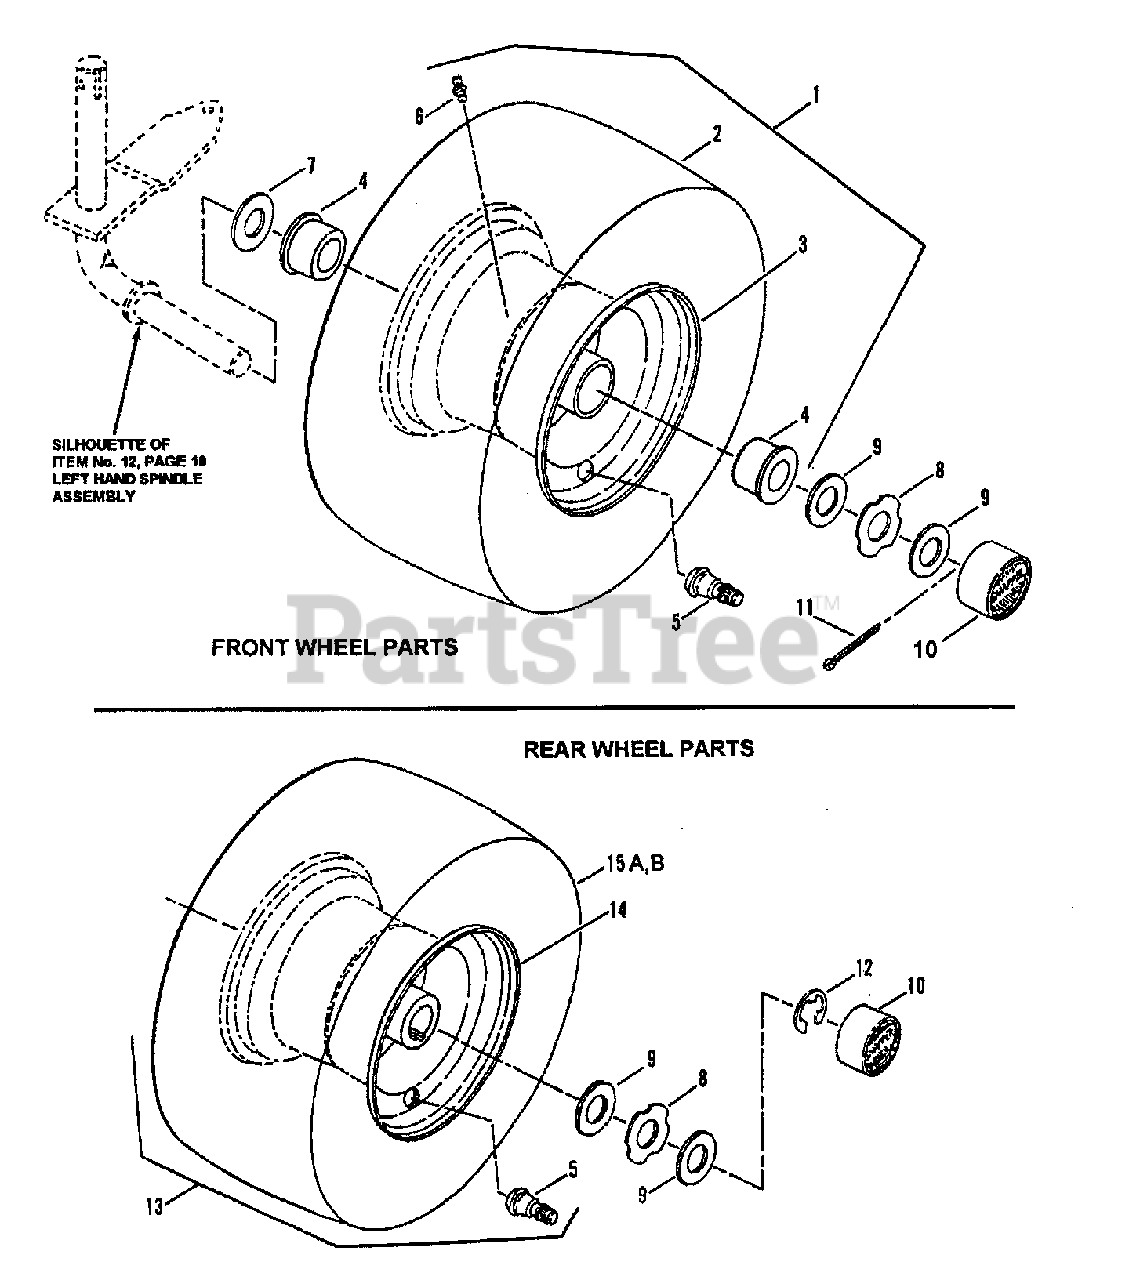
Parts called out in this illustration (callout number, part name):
1	ASSEMBLY, Front Tire & Rim
2	TIRE, 15 x 6.00
3	RIM, 6.00 x 3.50
3	RIM, 6.00 x 4.00 Grey
4	BEARING, Wheel
4	BEARING, Wheel Ball (Heim)
5	VALVE, Air (Snap-in)
6	FITTING, Lube 1/4-28 Tapered Thread
7	WASHER, Flat, 5/32 x 25/32" I.D. x 1-1/2" O.D.
8	WASHER, Hub-Cap Retaining
9	WASHER, Flat, 1/16 x 49/64 I.D. x 1-5/16" O.D.
10	HUB-CAP
11	COTTER-PIN, 5/32 x 1"
12	RING, External Retaining, 3/4"
13	ASSEMBLY, Rear Tire & Rim
14	RIM, 8 x 7.00
15A	TIRE, 18 x 9.50
15B	TIRE, 20 x 10.00
